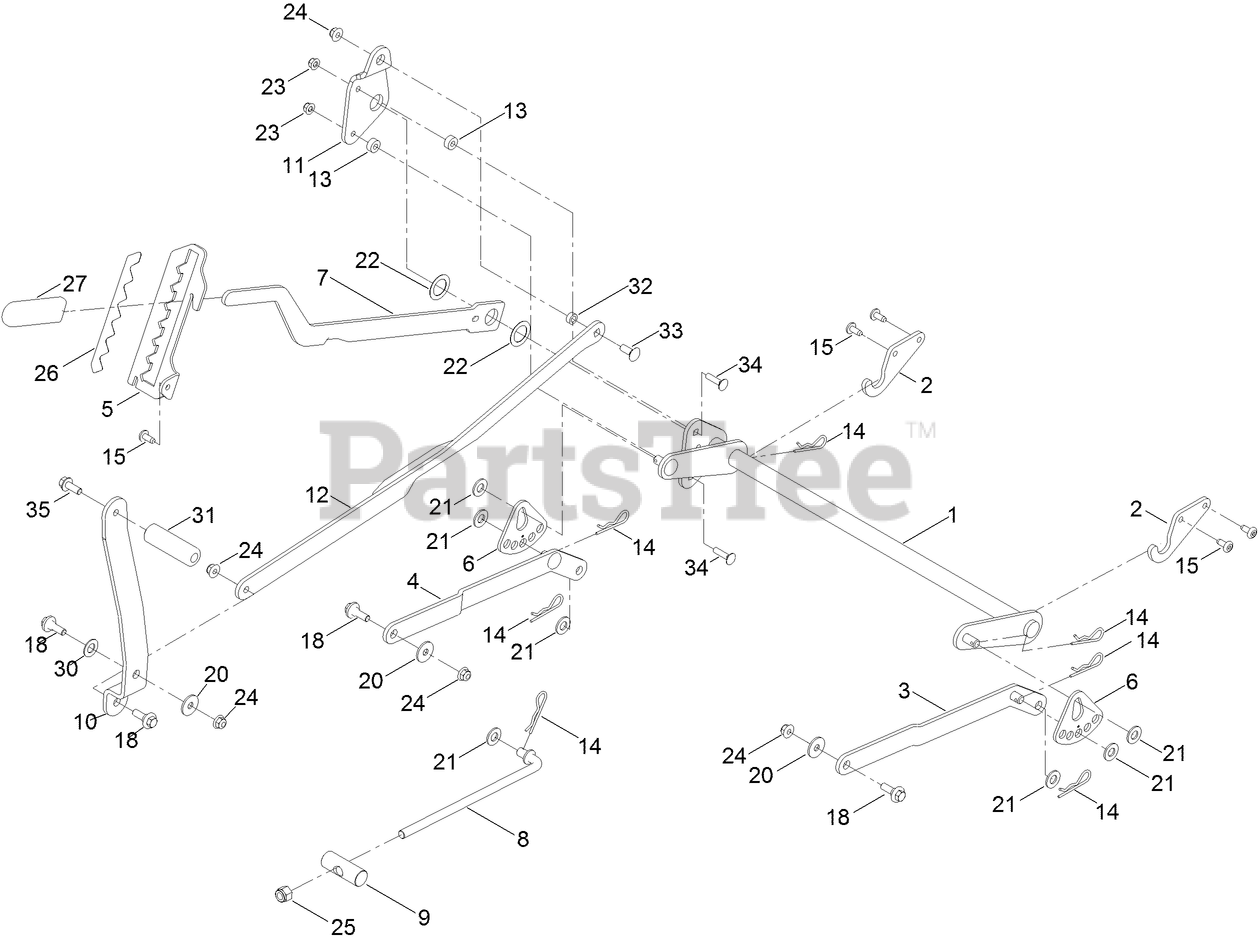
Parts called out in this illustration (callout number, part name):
1	DECK LIFT ASM
2	BRACKET-PIVOT, DECKLIFT
3	LH ARM ASM
4	RH ARM ASM
5	BRACKET-HOC
6	PLATE-ADJUSTMENT, HOC
7	LEVER-LIFT
8	ROD-MOUNT, DECK
9	PIN-PIVOT
10	PEDAL-LIFT
11	PLATE-FOOTLIFT
12	LINK ASM
13	SPACER
14	PIN-COTTER
18	SCREW-SHOULDER
20	WASHER-HARDENED
21	WASHER-FLAT
22	WASHER-THRUST
23	NUT-HF, NI
24	NUT-HF, NI
25	NUT-HEX
26	DECAL-HOC
27	GRIP-LEVER
30	WASHER-NYLON
31	PEDAL-FOOT LIFT
32	SPACER
34	SCREW-CARR
35	SCREW-HHF
